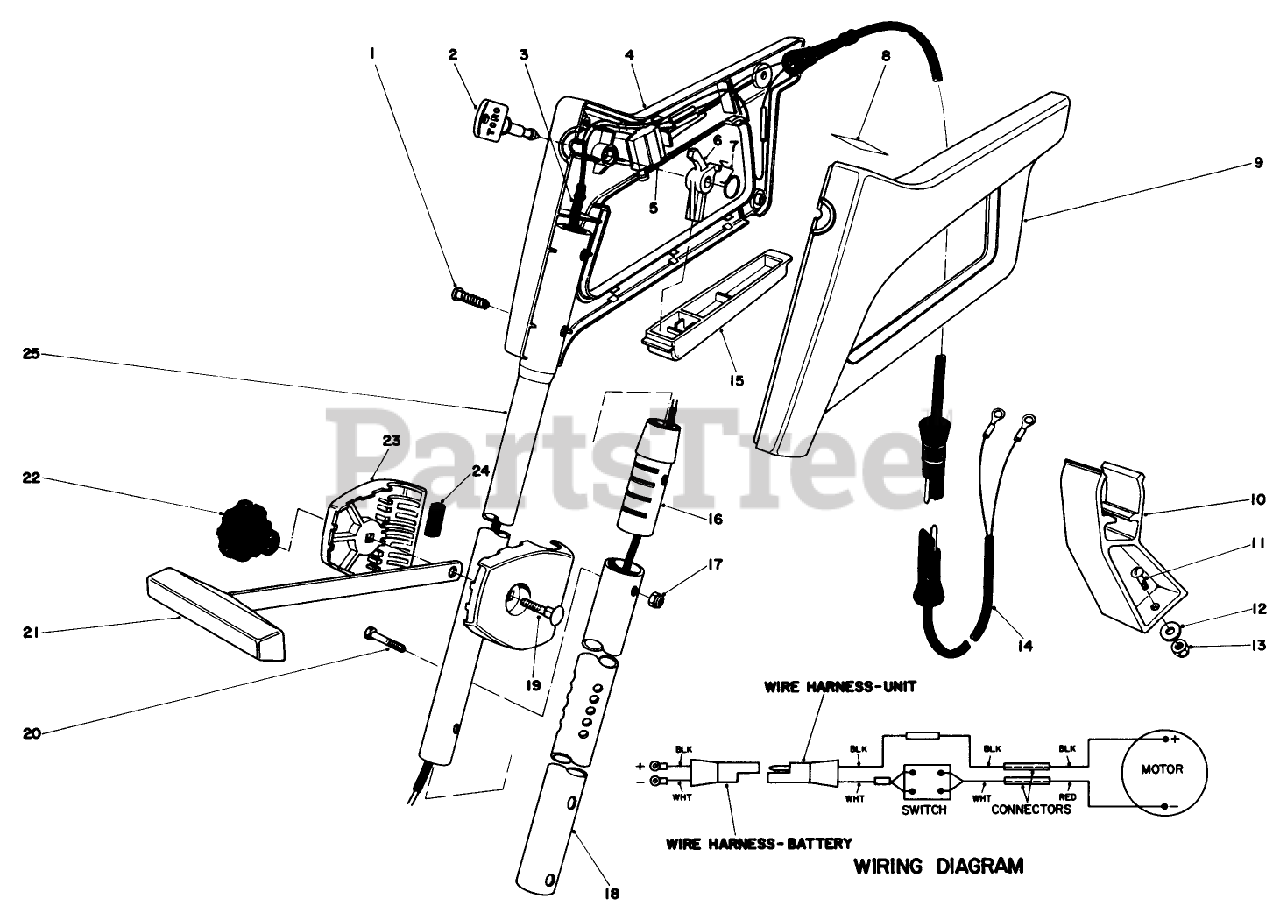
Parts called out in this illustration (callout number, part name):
1	Screw
3	WIRE HARNESS
4	Control Grip R.H.
5	SWITCH-STARTER
6	LOCKOUT
7	TORSION SPRING
8	Decal-12 Volt
9	Control Grip L.H.
10	Trimmer Clip
11	SCREW-HH
12	WASHER-FLAT
13	NUT-LOCK, NI
14	Wire Harness-Battery
15	SWITCH BAR,POWER SHOVEL
16	Tubing Sleeve
17	NUT-LOCK, NI
18	Lower Tube
19	BOLT-CARR
20	Screw
21	Tee Handle
23	Clam Shell (Incl. Ref. #24)
24	RUBBER INSERT
25	Tubing-Upper
